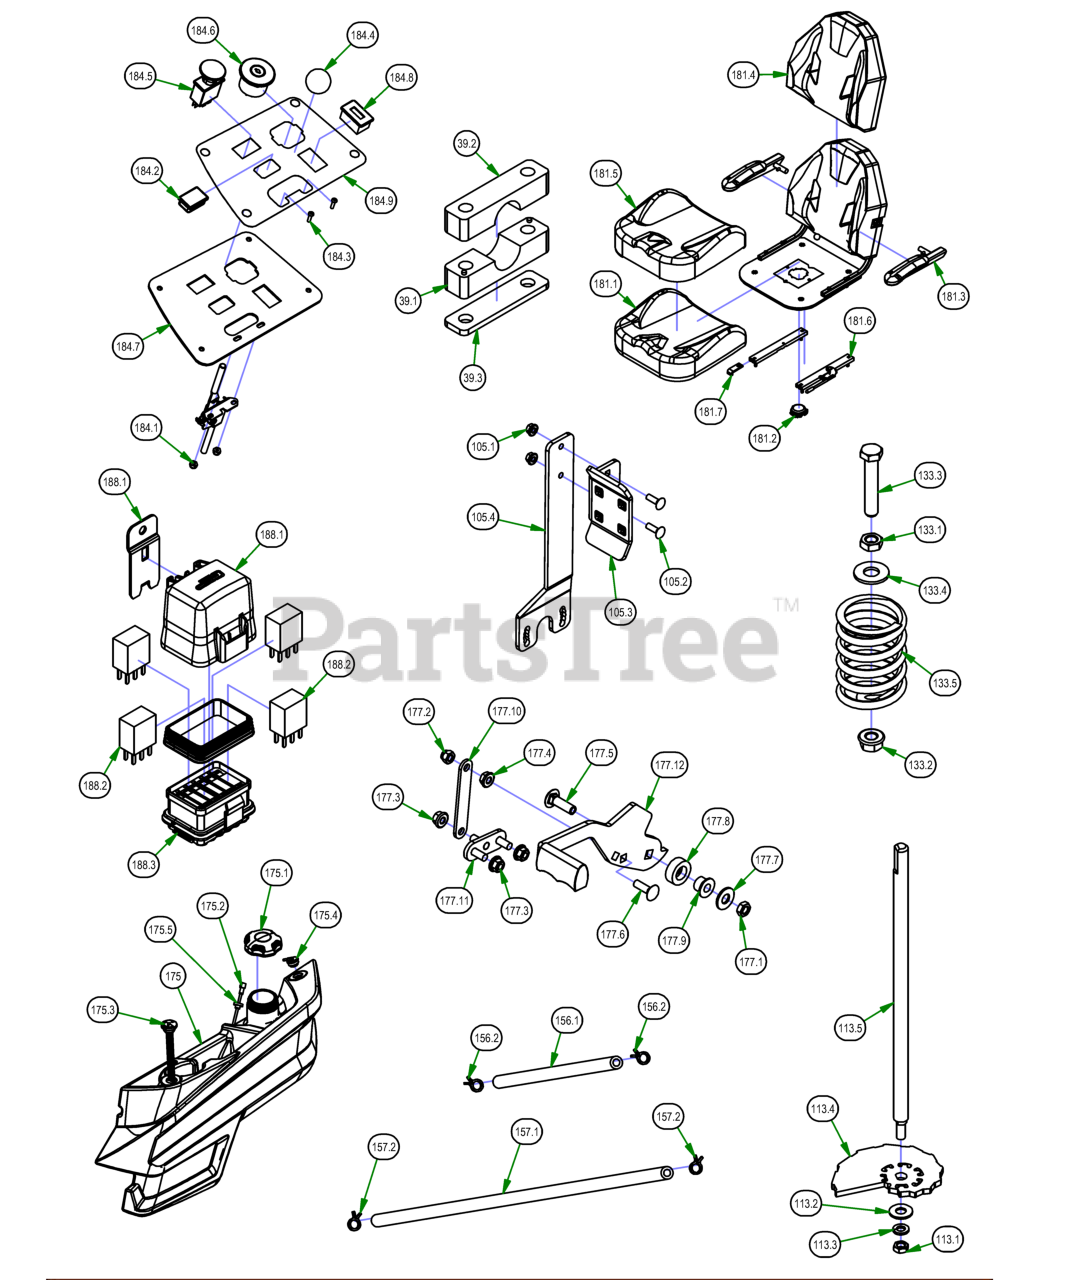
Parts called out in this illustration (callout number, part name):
39	Pillow Block Kit
39.1	Pillow Block MZ male
39.2	Pillow Block MZ female
39.3	Pillow Block Strap
105	Foot Pedal Assembly
105.1	5/16-18 NYLON INSERT FLANGE LOCKNUT ZINC
105.2	5/16-18 X 1 CARRIAGE BOLT (GR.8) ZINC
105.3	2017 MZ/ZT Shallow Foot Pedal
105.4	2017 MZ/ZT Deck Pedal Lever
113	ZT Deck Height Bar Assembly
113.1	3/8-24 HEX NUT ZINC YELLOW
113.2	3/8 FLAT WASHER USS (1" OD) ZINC
113.3	3/8 SPLIT LOCKWASHER ZINC
113.4	2017 MZ/ZT Cam Plate
113.5	2017 Deck Height Dial Rod ZT
133	Seat Spring Assembly
133.1	3/8-16 Half Jam Nut
133.2	3/8-16 HEX SERRATED FLANGE NUT HARD/ZINC
133.3	3/8-16 X 2 HEX CAP SCREW (GR.5) ZINC
133.4	3/8 FLAT WASHER USS (1" OD) ZINC
133.5	Seat Spring
156	15" Fuel Line Assembly
156.1	1/4 Fuel Line
156.2	1/4 Fuel Hose Clamp
157	37" Fuel Line Assembly
157.1	37" 1/4 Fuel Line
157.2	1/4 Fuel Hose Clamp
175	2021 Maverick Left Side Tank
175.3	Fuel Gauge w/Grommet
175.4	Rollover Valve W/Grommet
175.5	Pick-Up Grommet
177	2021 Load Balanced Brake Handle Assembly
177.1	3/8-16 HEX JAM 2-WAY REVERSIBLE CENTER LOCKNUT ZINC
177.2	5/16-18 NYLON INSERT CAP LOCKNUT ZINC (BLK CAP)
177.3	5/16-18 NYLON INSERT FLANGE LOCKNUT ZINC
177.4	5/16-18 HEX SERRATED FLANGE NUT HARD/ZINC
177.5	3/8-16 X 1-1/4 CARRIAGE BOLT ZINC
177.6	5/16-18 X 1 CARRIAGE BOLT (GR.8) ZINC
177.7	3/8 FLAT WASHER USS (1" OD) ZINC
177.8	2015 Brake Lever Spacer
177.9	.377 ID X .625 OD X .500 HGT X .880 FLNG DIA X .060 FLNG THK
177.10	Brake Cable Extension Plate
177.11	Brake Load Balancer Lower Weldment
177.12	Load Balanced Brake Handle with Grip
181	2021 ZT Elite Seat
181.1	Seat Cover Molded Foam for 071-2040-18/071-5080-18
181.2	13/14 MZ/Outlaw Seat Switch
181.3	2017 ZT/Maverick/2020 ZTElite/Avenger Arm Rest Kit
181.4	Back Cover for 071-2101-00
181.5	Seat Cover for 071-2101-00/071-2102-00
181.6	Seat Rails for Outlaw Seat/2020 ZT Elite/ZTAvenger
181.7	Black Seat stop from Seat King
184	2019 ZT/Maverick Control Panel Assembly
184.1	10-24 Nylon Insert Locknut Zinc Orange Nylon
184.2	Light Plug
184.3	10-24 X 5/8 BS Button Head Bolt
184.4	Throttle Lever Assembly
184.5	PTO Engager
184.6	Ignition Switch
184.7	Control Panel
184.8	Tachometer
184.9	2018 MZ/Magnum/ZT/Maverick Control Panel Decal
188	Wiring Harness
188.1	Relay Block Cover Replacement Kit
188.3	Wiring Harness
